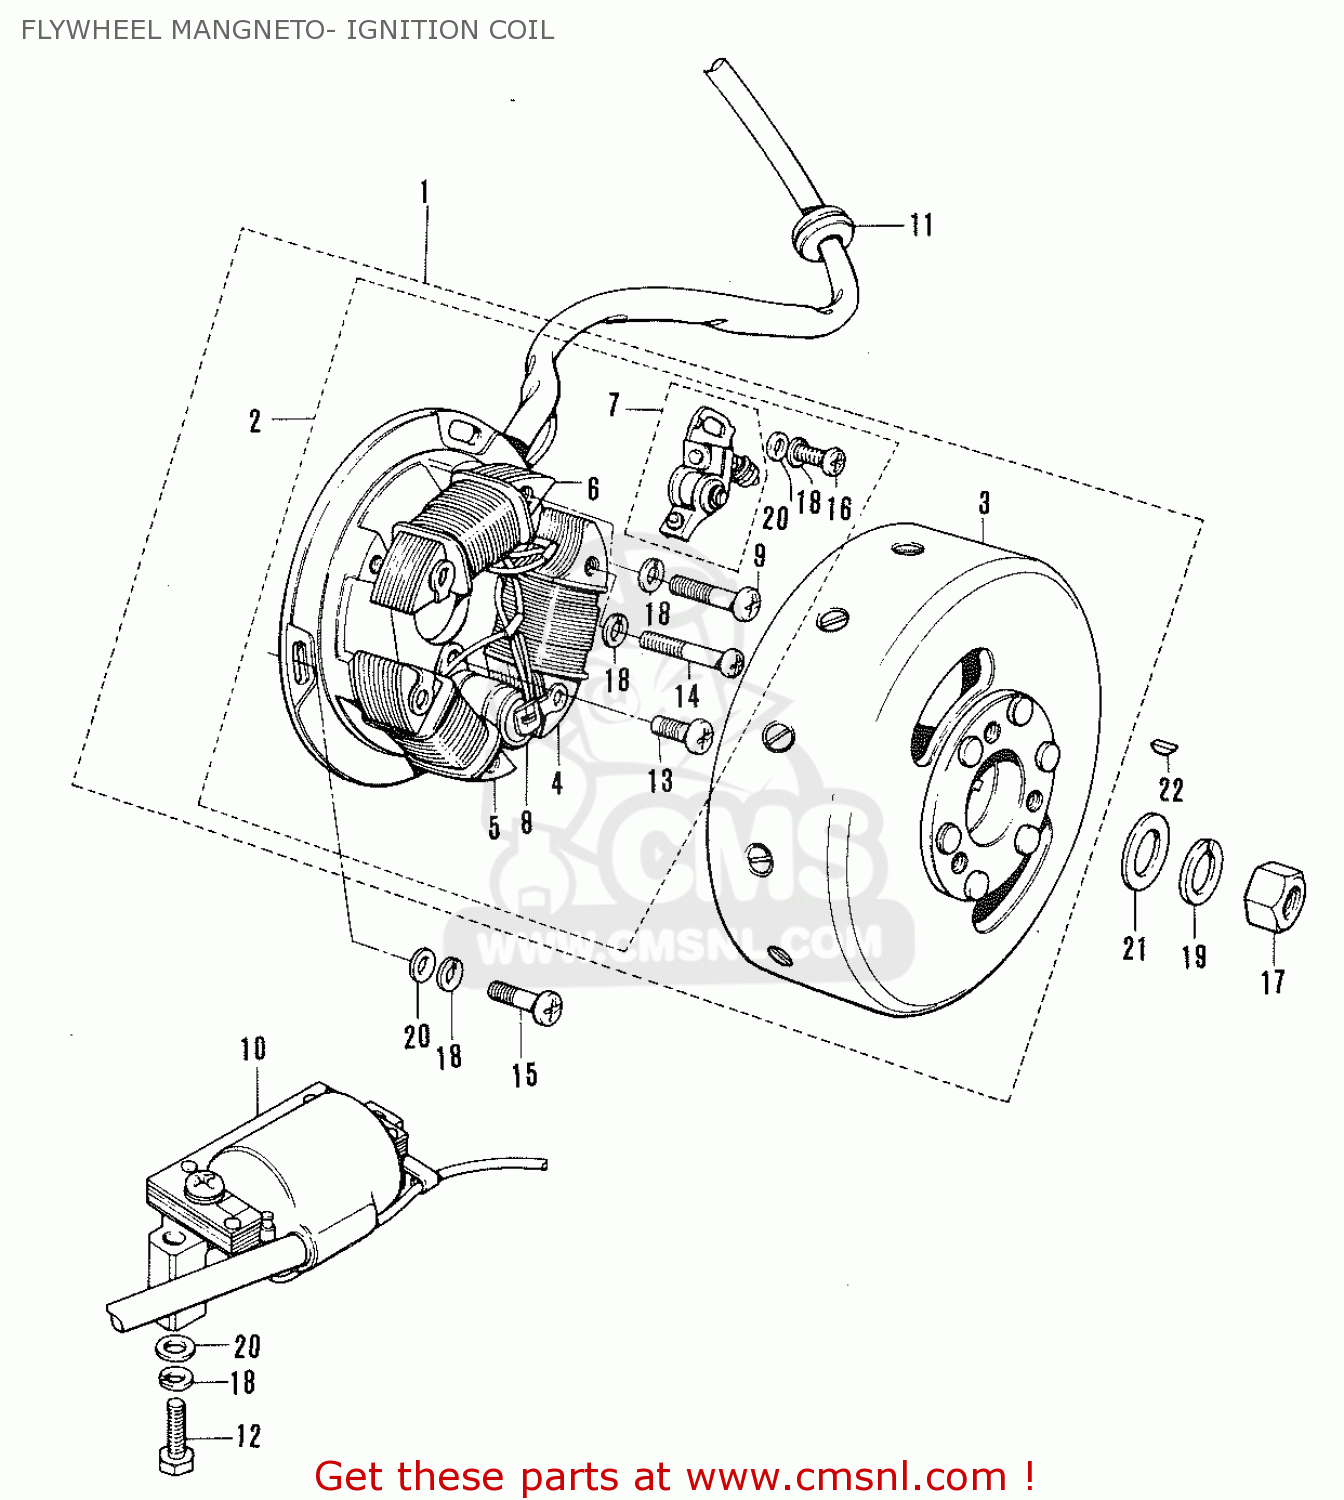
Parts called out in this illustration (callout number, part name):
1	MAGNETO ASSEMBLY
2	STATOR ASSEMBLY
3	ROTOR ASSEMBLY
4	COIL,LIGHTING
5	COIL
6	COIL,PRIMARY
7	POINT ASSY,CONTACT
8	CONDENSER
9	PRIMARY COIL FITTING SCREW
10	COIL ASSEMBLY,IGNITION
11	GROMMET
12	BOLT
13	SCREW
14	SCREW
15	SCREW
16	.SCREW
17	NUT
18	LOCK WASHER
19	WASHER,LOCK 12
20	WASHER
21	WASHER
22	KEY 4MM
